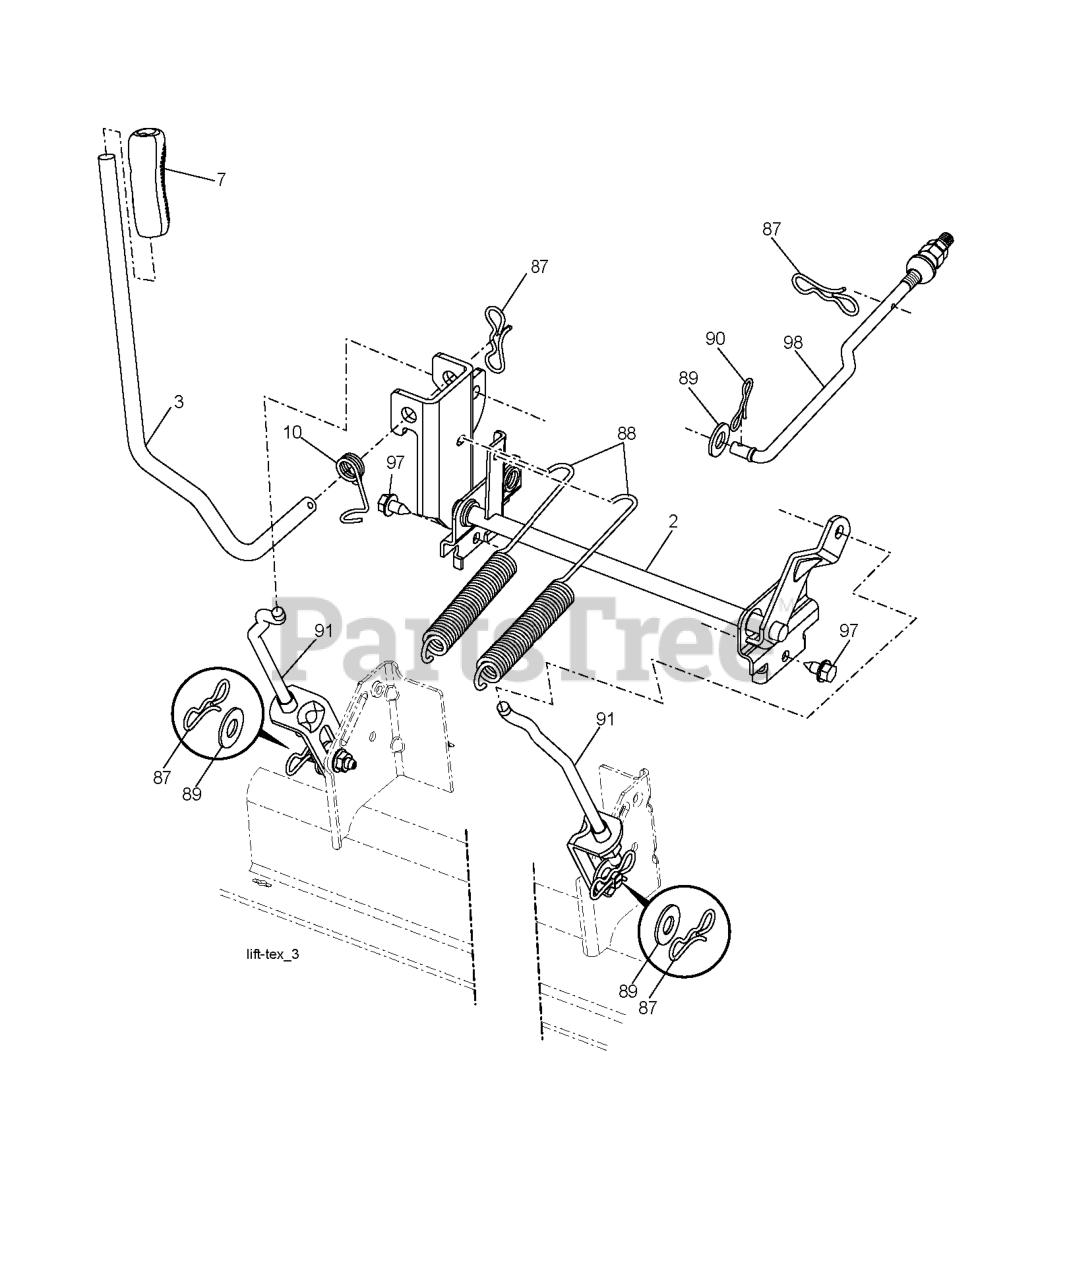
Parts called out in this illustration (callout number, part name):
2	SHAFT.ASM.LIFT.CROSS.H
3	LEVER.LIFT.HANDLE.GT
7	GRIP.HANDLE.LIFT.PVC.BLACK
10	SPRING.TORSION.LIFT.HANDLE
87	PIN.COTTER.7/16.BOW TI.
88	SPRING.LIFT.ASSIST
89	WASHER.CLEAR.ZINC
90	PIN.COTTER.5/16.BOW TI
91	LINK.LIFT.ASM.REAR.GT.
97	SCREW, 3/8-16X3/4
98	LINK.ASM.SUSP.FRONT.MWR.10.5
